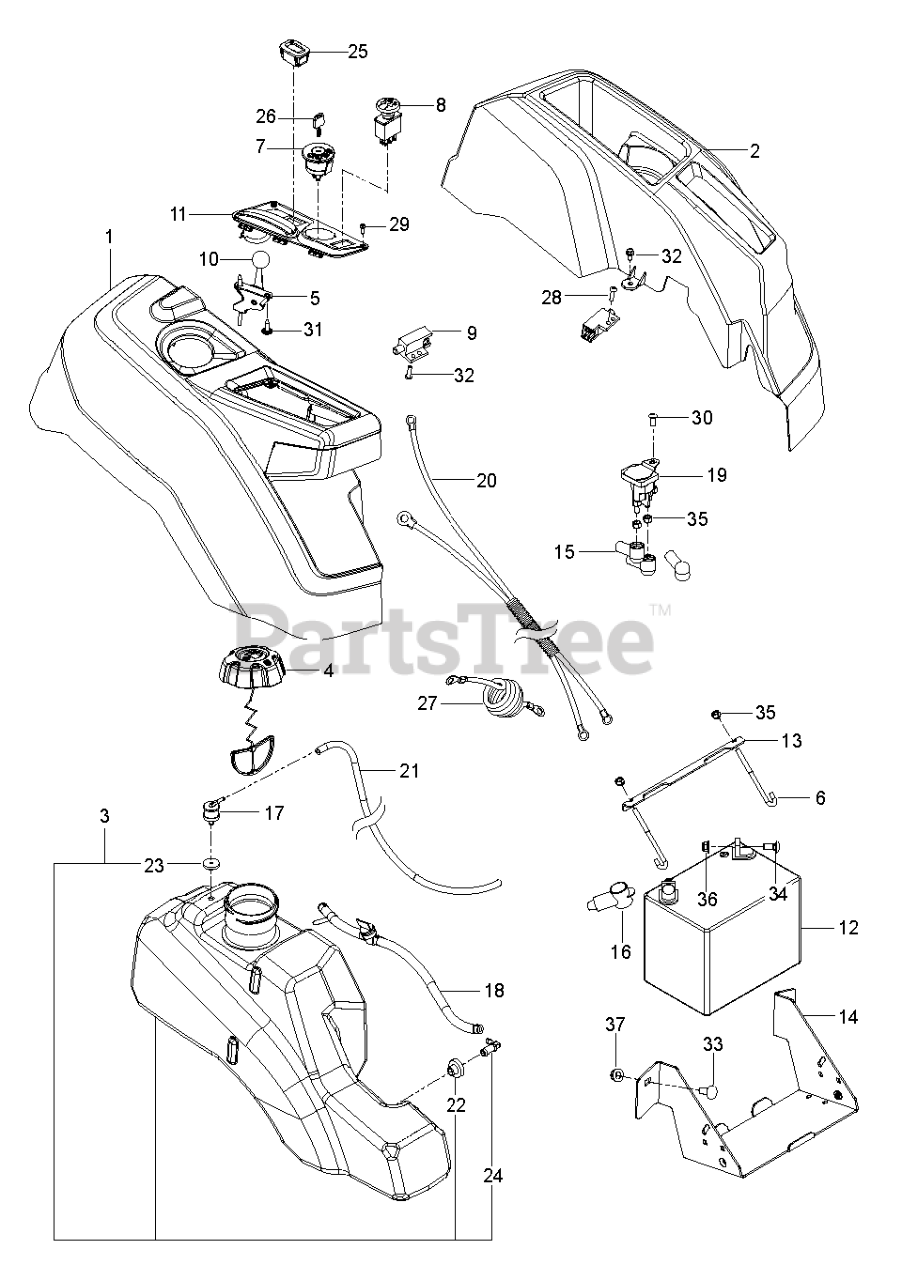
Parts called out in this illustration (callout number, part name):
1	CONSOLE.ASSY.RZ.REFRESH.RH
2	CONSOLE.LH.ASM
3	ASM.FUEL.TANK.LG.3".W/O SHIELD
4	CAP ASSY FUEL 3" GRAY
5	CABLE.THROTTLE.37"
6	HOOK.J.BATTERY
7	RP IGNITION SWITCH
8	RP SWITCH.PTO.TERMINAL.STD.RED
9	SWITCH.INTLK.RZ.RFRSH.BUTTON
10	KNOB.ROUND.BALL.BLACK
11	CONTROL.PANEL.RZ.REFRESH.RH
12	BATTERY, 12 V 300 AMP DRY
13	BRACKET.PNT.MOUNT.BATTERY.EDIP
14	BOX.PNT.BATTERY.RZ.EDIP
15	TERMINAL COVER
17	VALVE.FUEL.CHECK
18	FUEL.HOSE.SHUT.OFF.ASM.10".3"
19	SOLENOID.STARTER.BRASS.PLUNGER
20	HARNESS.BTTRY.CABLE.RZ.REFRESH
21	HOSE.3/16".VAPOR.LINE.23"LGTH
22	BUSHING OUTLET T
23	GROMMET.ROV.SENTEC
24	STEM FUEL TANK
25	GUAGE.SRVCMNDR.HRMTR.
26	KEY MLD GEN DELTA
27	CABLE POSITIVE, LONG
28	SCREW.BUTTONHD.10-24X1/2.(2 2)
29	SCREW 6-19X.437
30	SCR 1/4-20 X 5/8 BTN SKT HD ZD
31	SCREW.PAN.HEAD.#10
32	SCREW
33	RHSNB 3/8C X 1
34	RP BOLT 5/16-18 X3/4 ZN/YEL GR
35	NUT.1/4-20.HEX.NYLOC.ZD
36	5/16-18 NYLOC FLANGE NUT
37	NUT 3/8-16 HEX FLG NYLOC ZD
